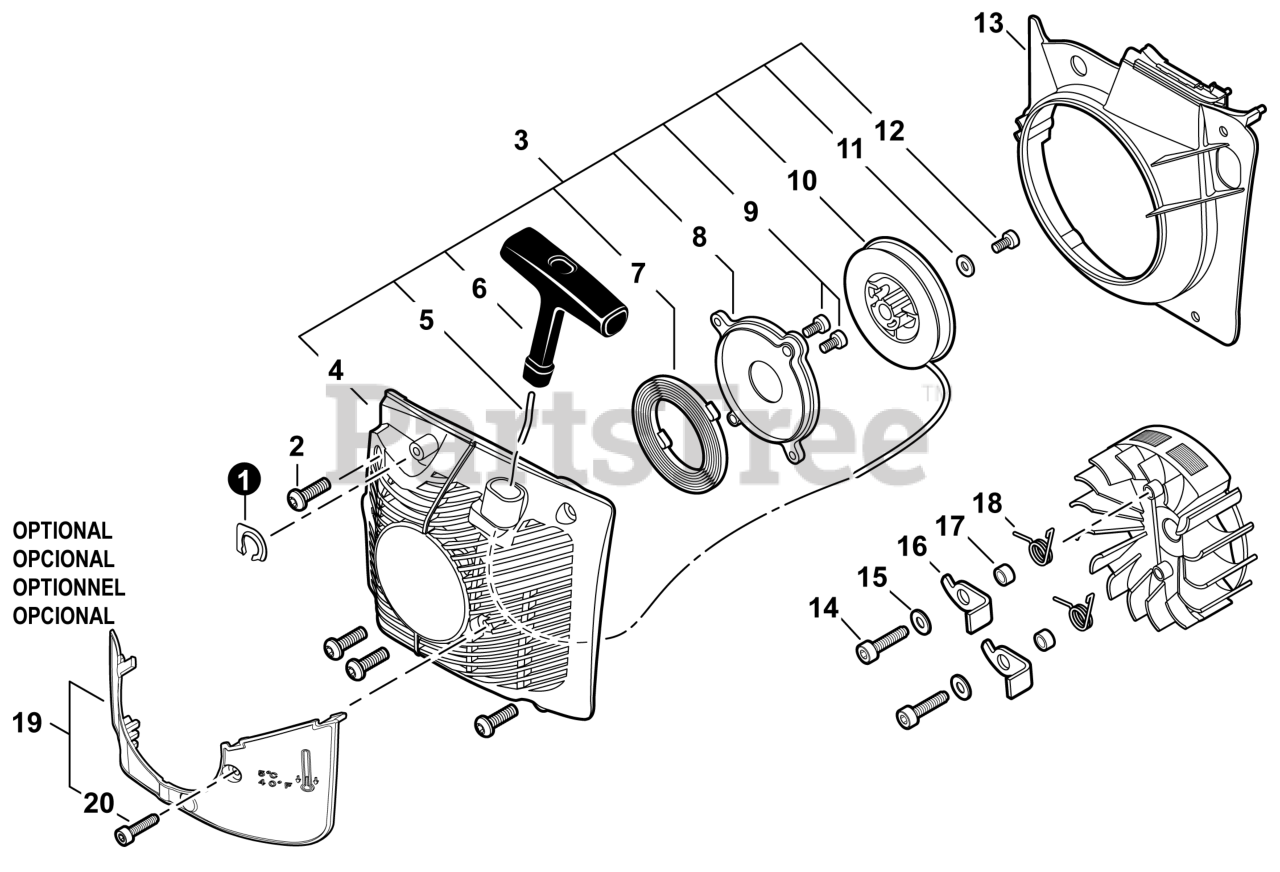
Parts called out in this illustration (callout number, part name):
1	PLATE, EYE
2	BOLT, TORX 5x20
3	STARTER ASSY, RECOIL
4	CASE, STARTER
5	ROPE, STARTER 4x950
6	GRIP, STARTER
7	SPRING, RECOIL
8	PLATE, STARTER
9	BOLT, TORX 4x12
10	REEL, ROPE
11	WASHER 5.2x16x1.0
12	BOLT, TORX 5x10
13	COVER, FAN
14	BOLT, TORX 5x16
15	WASHER 5.5x12x0.8
16	PAWL, STARTER
17	SPACER 5.2x8x2.1
18	SPRING, TORSION
19	SHIELD KIT - SNOW
20	BOLT, TORX 4x12
